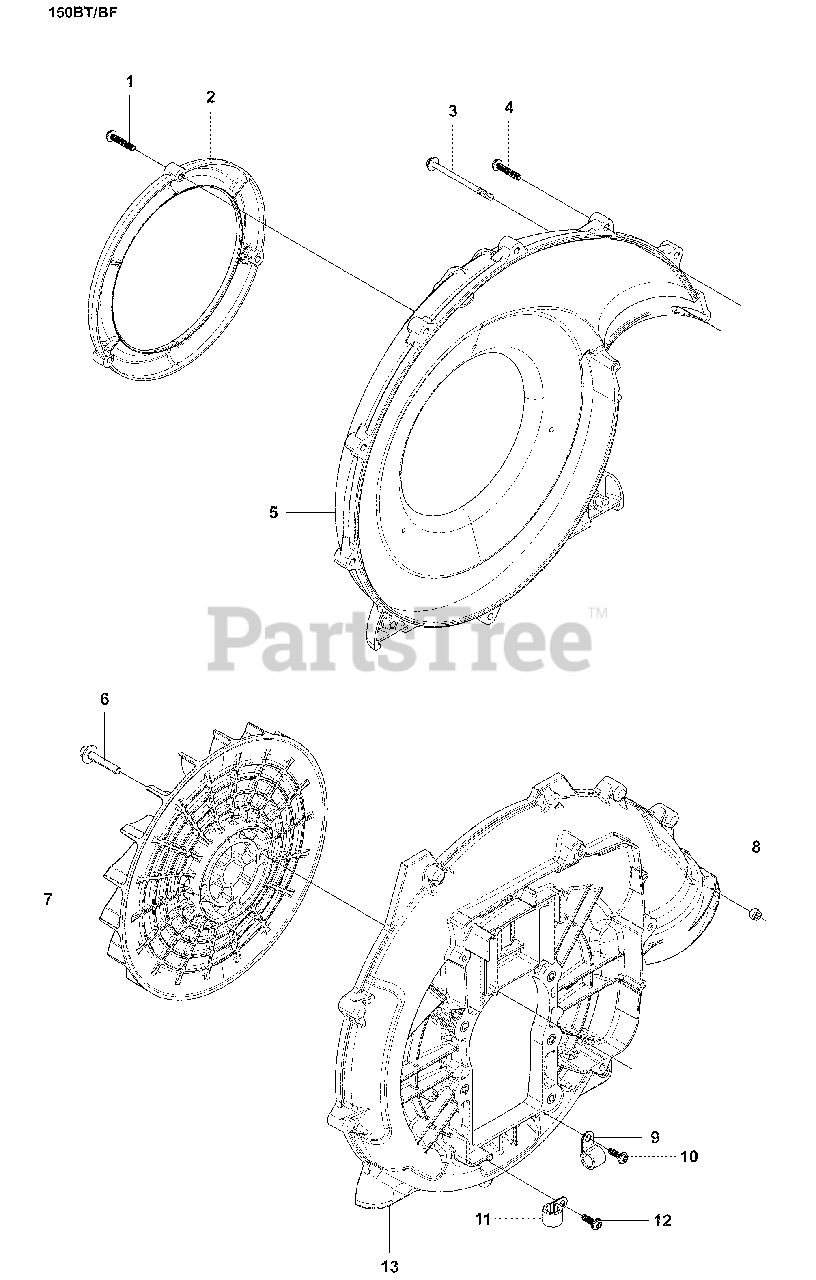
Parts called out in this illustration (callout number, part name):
1	SCREW
2	FUNNEL
4	SCREW
5	VOLUTE COVER
6	RP_BOLT
8	NUT
10	SCREW
11	RP_CLAMP
12	SCREW
13	FAN HOUSING
